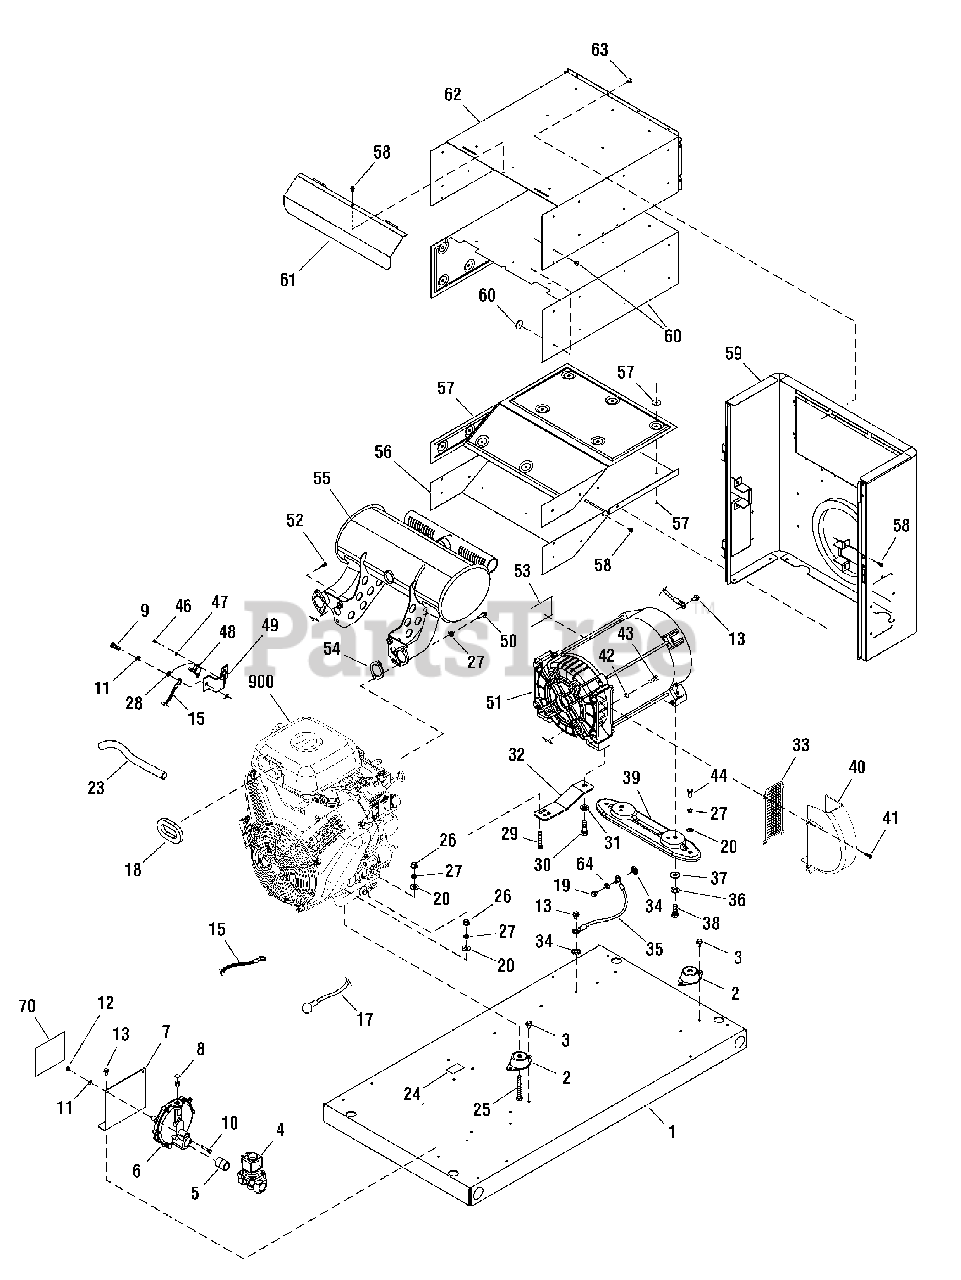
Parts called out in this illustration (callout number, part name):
2	MOUNT, Vibration
4	SOLENOID, Gas Fuel
6	REGULATOR, NG / LPG
7	BRACKET
9	* CAPSCREW, Hex Head, M6 - 1 x 16
10	* CAPSCREW, Hex Head, M6 - 1 x 30
11	* WASHER, Lock, 1/4
12	* NUT, M6 - 1
13	BOLT
15	CABLE, Battery, Black
17	CABLE, Battery, Red
18	TUBE
20	* WASHER, Flat, 5/16 - M8
23	HOSE, Oil Drain
24	DECAL
25	* CAPSCREW, Hex Head, 5/16-18 x 2-1/2
26	* NUT, 5/16-18
27	* WASHER, Lock, 5/16 - M8
29	* CAPSCREW, Hex Head, 5/16-18 x 2
30	* CAPSCREW, Hex Head, M12 - 1-3/4 x 35
31	* WASHER, M12
32	SUPPORT, Engine
34	* WASHER, Shakeproof, M6 - 1/4
36	* WASHER, Lock, 3/8
37	* WASHER, Flat, 3/8
38	* CAPSCREW, Hex Head, 3/8-16 x 1
39	SUPPORT, Engine
41	* SCREW, Taptite, M5 - 0.8 x 10
42	* WASHER, Lock, 3/8
43	* CAPSCREW, 3/8-16 x 1-1/4
44	* CAPSCREW, Hex Head, 5/16-18 x 3/4
46	* SCREW, Phillips Head, 4-40 x 0.19
47	* WASHER, Lock, #4
49	PLATE, Temp Switch
50	SCREW
51	ALTERNATOR ASSEMBLY
53	DECAL, Warning, Burn Hazard
59	BULKHEAD, Alternator
62	BOX, Muffler Top
64	* WASHER, Shakeproof, M6
70	DECAL, Fuel Requirements
900	** ENGINE
